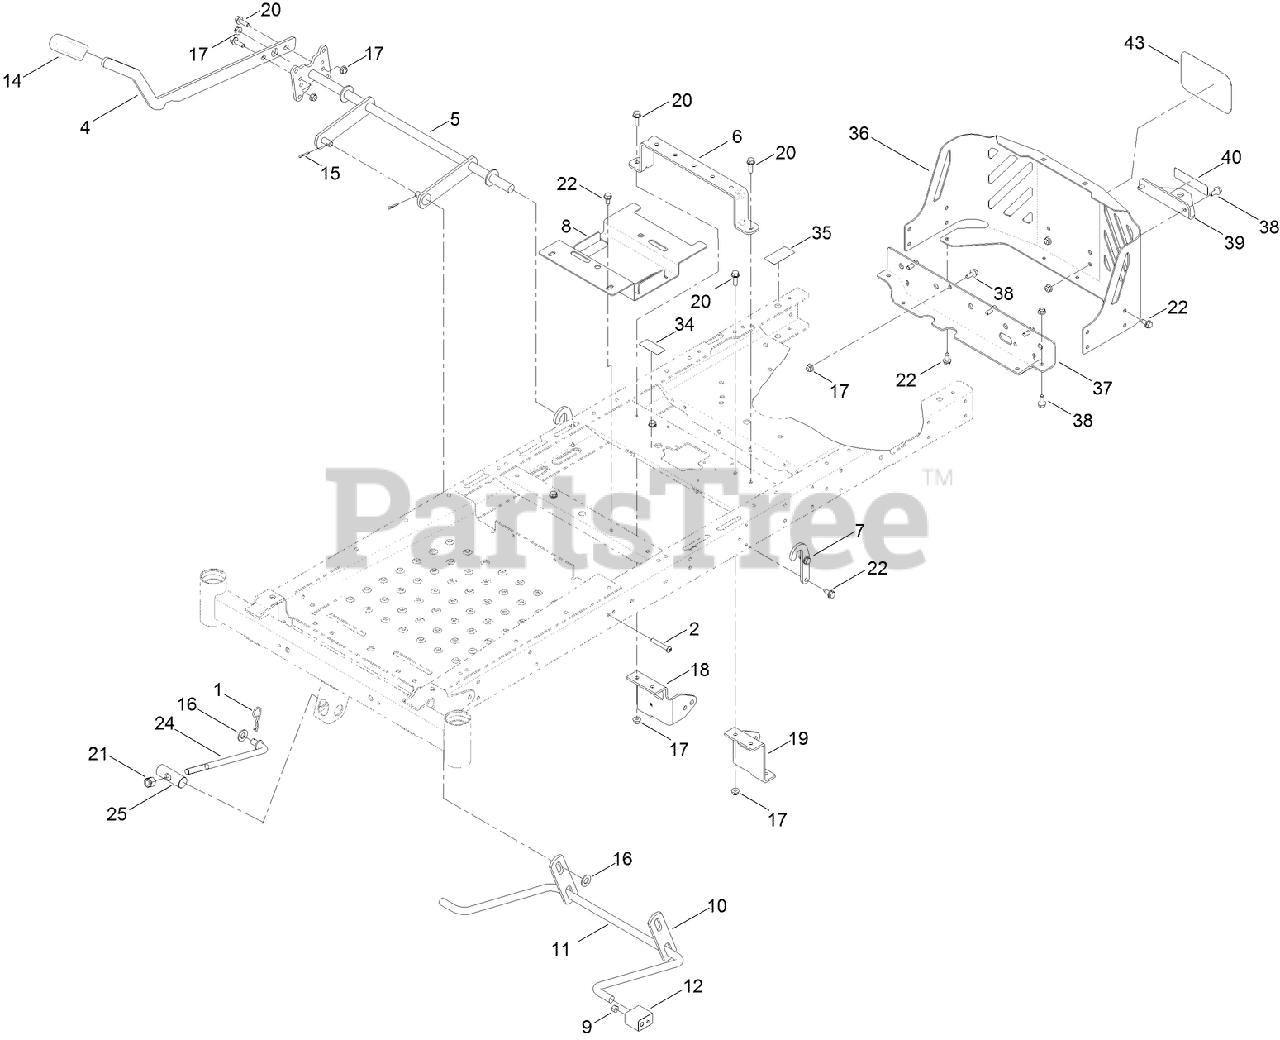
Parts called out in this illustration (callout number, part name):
1	PIN-COTTER
2	SCREW-HSBH
4	LEVER-LIFT
5	LIFT-DECK, NARROW
6	BRACE-SEAT, REAR (NARROW)
7	BRACKET-LIFT
8	BRACKET-BATTERY
9	NUT-LOCK, NI
10	LINK-LIFT
11	ARM-LIFT, REAR
12	BLOCK-PIVOT
14	GRIP-LEVER
15	PIN-COTTER
16	WASHER-FLAT
17	NUT-HF, NI
18	MOUNT-HYDRO, FRONT (RH)
19	MOUNT-HYDRO, FRONT (LH)
20	SCREW-HHF
21	NUT-HEX
22	SCREW-HWHTF
24	ROD-MOUNT, DECK
25	PIN-PIVOT
34	DECAL-LOCATION, SERVICE DEALER
35	DECAL-BYPASS
36	GUARD-ENGINE, NARROW
37	CROSSMEMBER-REAR, NARROW
38	SCREW-HHF
39	BRACKET-HITCH
43	DECAL
